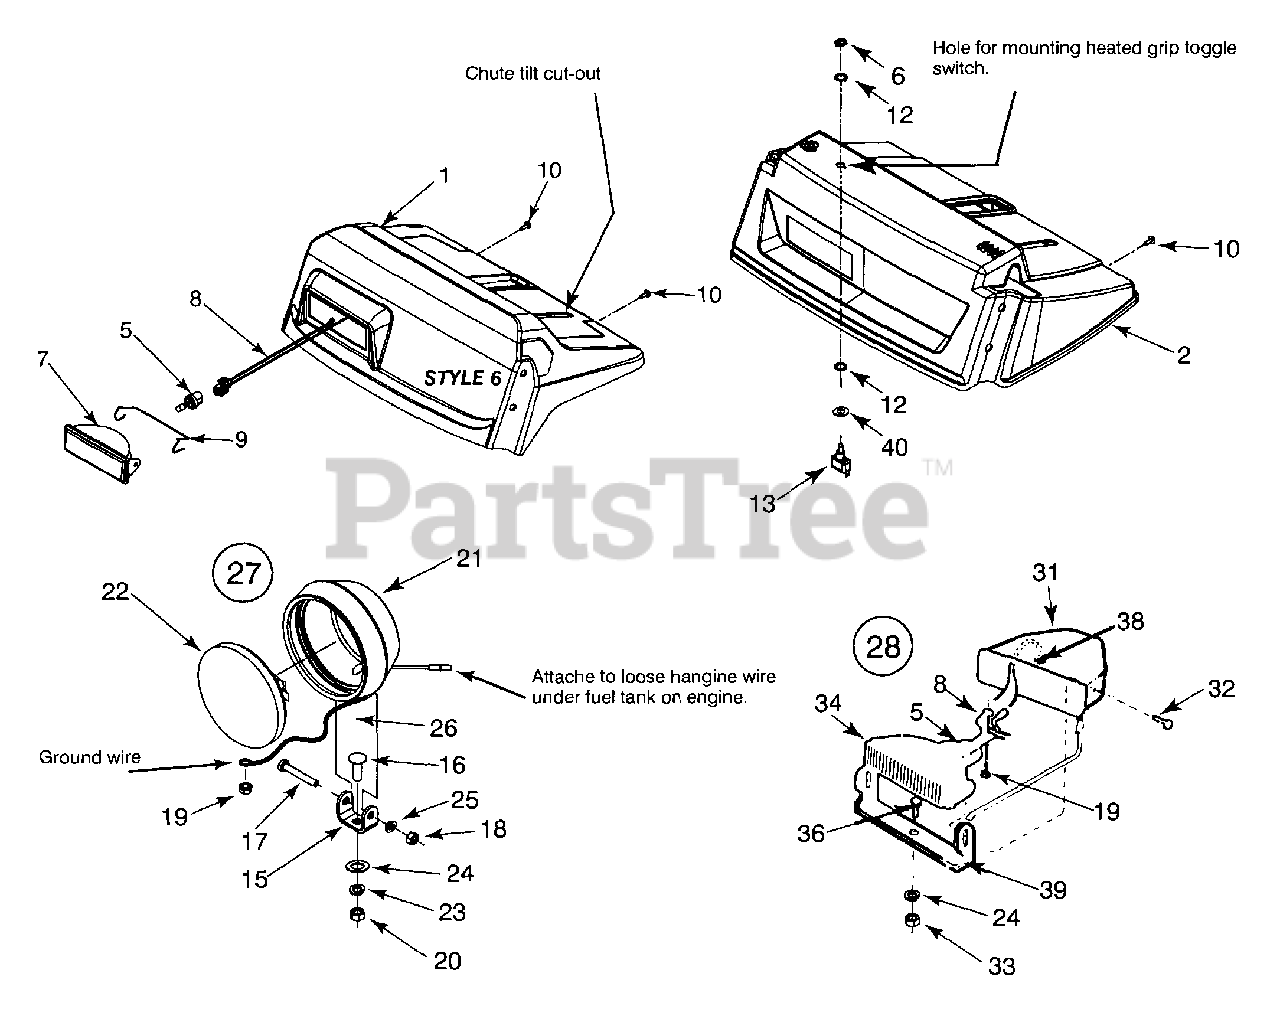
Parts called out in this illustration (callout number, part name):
2	Black Handle Panel
3	Grey Handle Panel
4	Black Handle Panel
5	Bulb #890, 12 V, 27 Watt
6	Hex Nut
7	Headlight Housing
8	Wire Harness
9	Retainer
10	Hex Tapp Wash Hd. Scr. #10 x 5/8
12	Lock Ring - Toggle Switch
13	Toggle Switch,Single Throw (heated grips)
15	Mounting Lamp Bracket
16	Carriage Bolt 5/16-18 x 1.00" Lg
17	Hex Screw 1/4-28 x 1.75 Gr 5
18	Hex Nut 1 /4-28 Gr 5
19	Sems Hex Nut 1 /4-20
20	Hex Nut 5/16-18 hd. Gr. 5
21	Lamp Housing
22	Sealed Beam 18 Watt CGE #4414-1
23	L-Wash 5/16 ID
24	Flat Washer.349 ID X .879 OD X .063
25	L-Wash 1/4 ID
26	Ground Wire
27	Top Mount 18 watt Lamp Ass'y (sealed beam)
28	Top Mounting Halogen Lamp Assembly
31	Halogen Lamp Housing
32	Phillips Pan Hd. Scr. M4 x 16mm
33	Hex Ins Locknut 5/16-18
34	Lamp/Lens Housing Ass'y
36	Carriage Bolt 5/16-18 x .75
38	Grommet.38 ID X .50 OD X .12
39	Lamp Mounting Brkt.
40	Flat Washer.474 ID x .879 OD x .064
